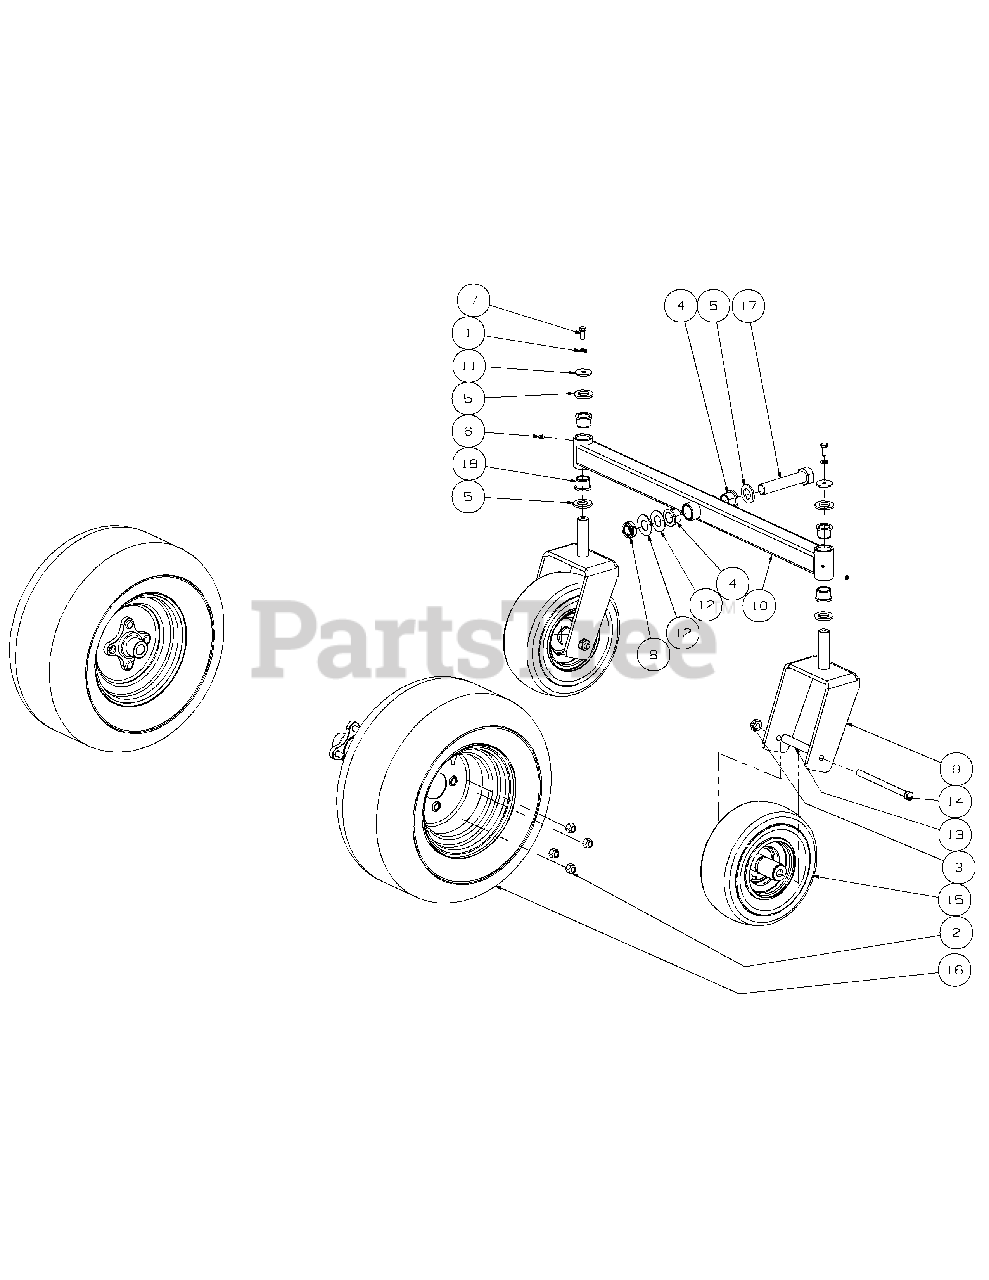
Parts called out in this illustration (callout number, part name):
1	Lock Washer, 3/8 Zinc
2	Lug Nut, 1/2-20
3	Lock Nut, Nylon insert, 1/2-20
4	Flange Bearing, 1.001 ID
5	Washer Special
6	Grease Fitting, 1/4-28 x 3/16
7	Hex Cap Screw, 3/8-16 x .88
8	Nut Jam, 1.0-14, Nylon Insert
9	Castor Wheel Mounting Bracket
10	Front Axle Assembly
11	Flat Washer, .390 x 1.5 x .134
12	Flat Washer, 1.00 ID x 2.25 OD x ,075
13	Spacer, .54 ID x .75 OD x 5.925 Lg
14	Hex Cap Screw, 1/2-20 x 7.50
15	Wheel Assembly 11 x 6.00 - 5, Beige
16	WHeel Assembly 20 x 10.00 - 10
17	Hex Cap Screw, 1-14 x 5.5
18	Flange Bearing, 1.0 ID
